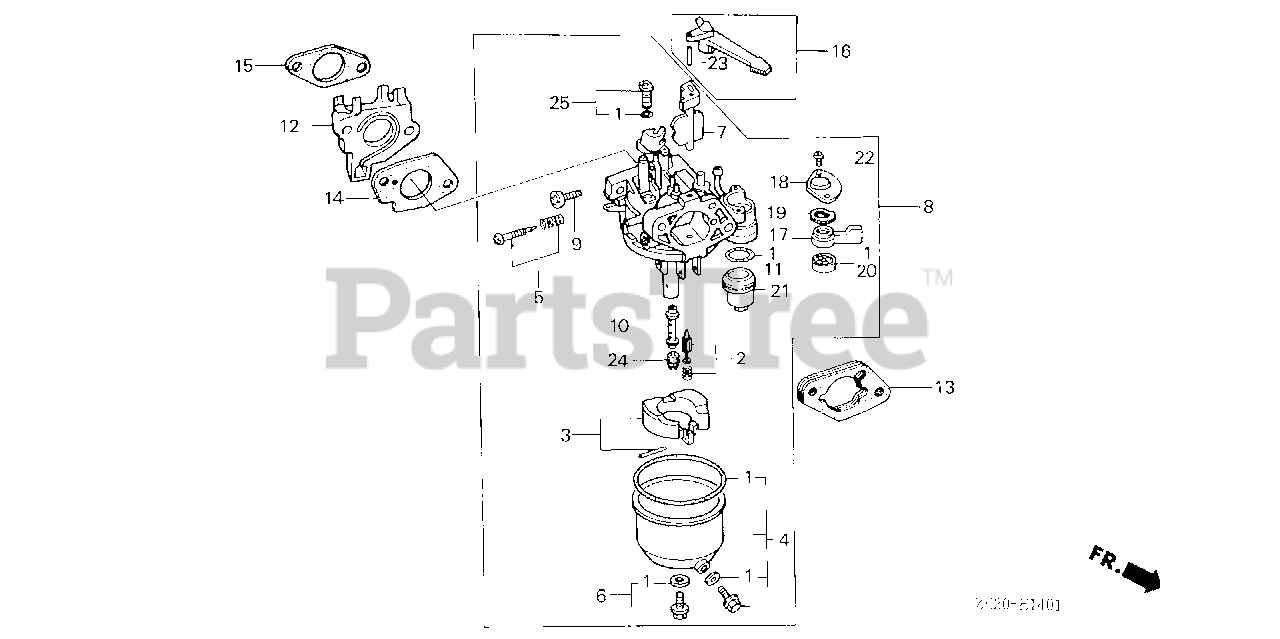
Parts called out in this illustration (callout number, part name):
1	GASKET SET (CARBURETOR NO.)
1	GASKET SET (CARBURETOR NO.) (INCLUDES 16173-001-004)
2	VALVE SET, FLOAT
4	CHAMBER SET, FLOAT
5	SCREW SET, PILOT
6	SCREW SET
8	CARBURETOR ASSY. (BE15B C)
8	CARBURETOR ASSY. (BE15B E)
9	SCREW, THROTTLE STOP
10	NOZZLE, MAIN
11	GASKET, FUEL STRAINER CUP
12	INSULATOR, CARBURETOR
13	SPACER, CARBURETOR
14	GASKET, CARBURETOR
14	GASKET, CARBURETOR (CARBURETOR NO.)
15	GASKET, INSULATOR (CARBURETOR NO.)
16	LEVER, CHOKE (STD)
17	LEVER, VALVE
17	LEVER, PETCOCK
18	PLATE, LEVER SETTING
19	SPRING, PETCOCK LEVER
20	GASKET, PETCOCK (CARBURETOR NO.)
21	CUP, FUEL STRAINER
22	SCREW, PAN (3X8)
23	PIN, SPRING (2X12)
24	JET, MAIN (#82) (CARBURETOR NO.)
24	JET, MAIN (#85) (CARBURETOR NO.)
24	JET, MAIN (#88)
25	JET SET, PILOT (#38)
